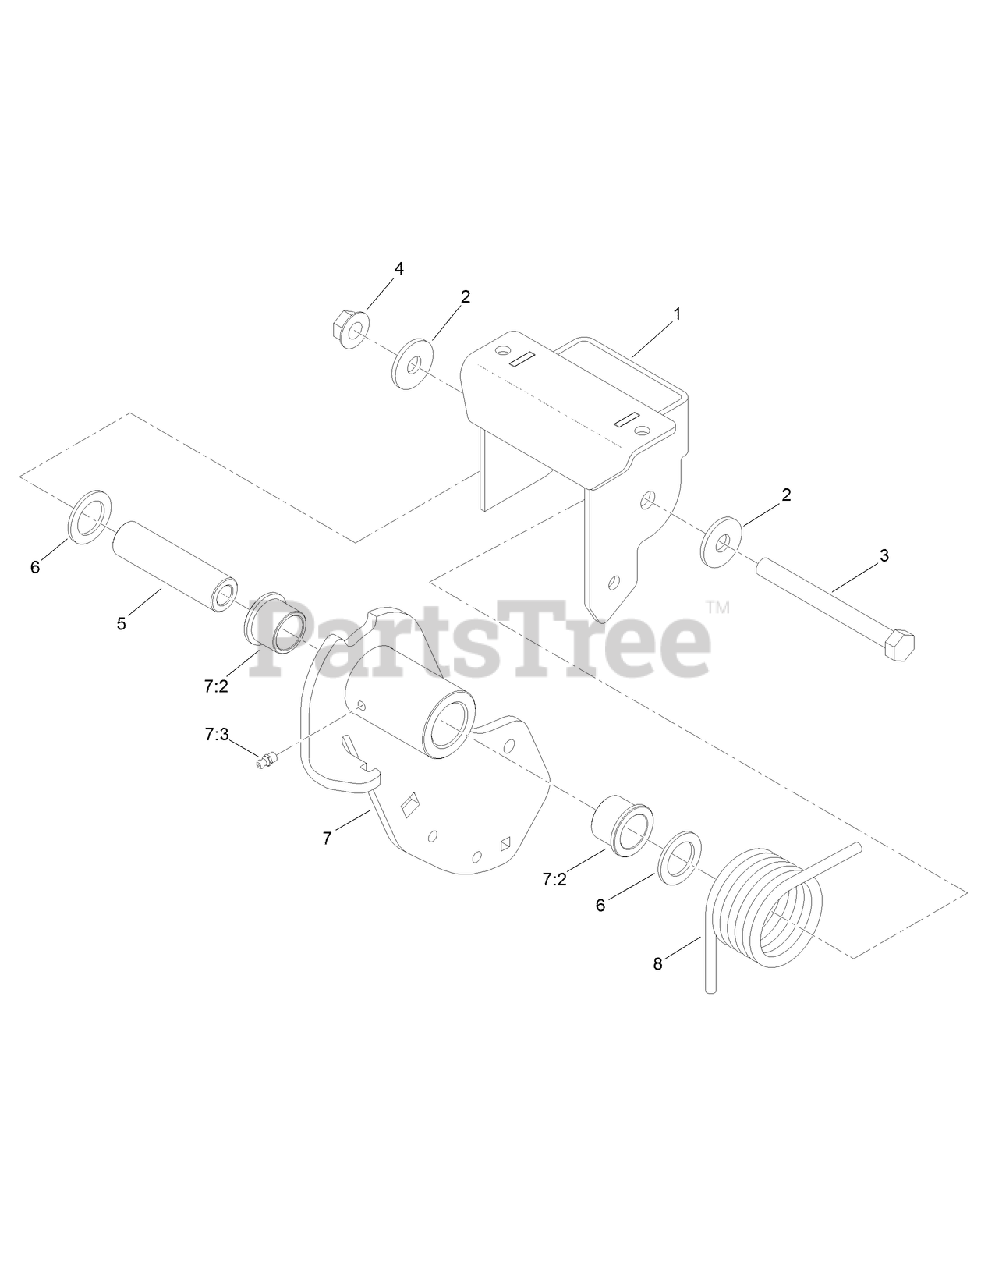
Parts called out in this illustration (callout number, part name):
1	BRACKET-TENSIONER, IDLER
2	WASHER-SUPPORT
3	SCREW-HH
4	NUT-HF
5	SPACER-PLAIN
6	SPACER-HARDENED
7	IDLER TENSIONER ARM ASM
7:2	BUSHING-FLANGE
7:3	FITTING-GREASE
8	SPRING-TORSION
